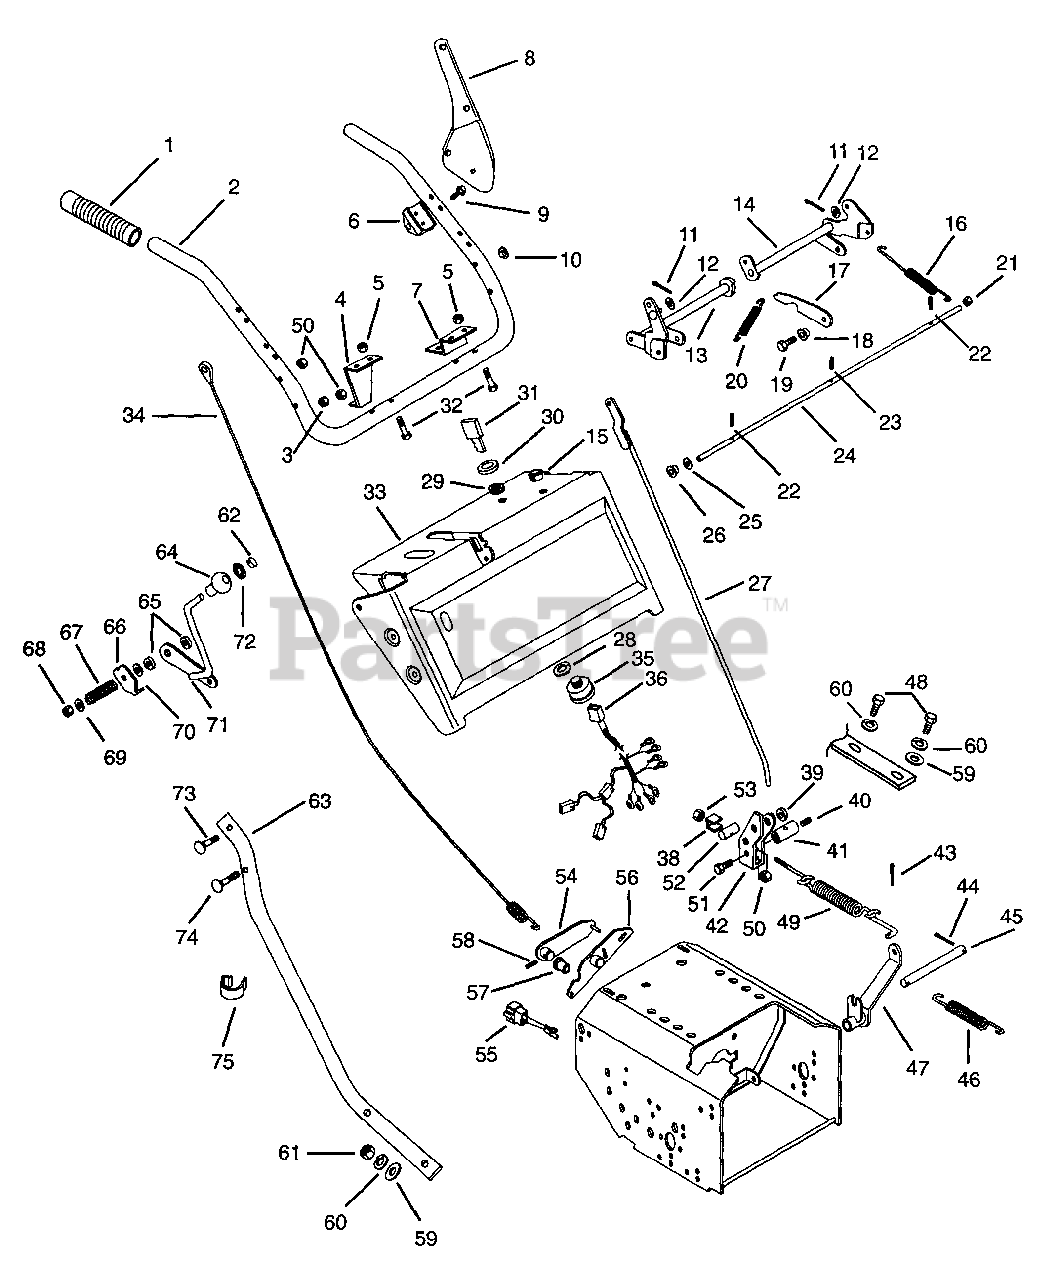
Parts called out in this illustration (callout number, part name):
1	HANDLE GRIP
2	UPPER HANDLEBAR
3	@NUT-SPNLK-FLG .312-18 YWZC
4	BRACKET, ROD
5	@NUT-LK-CTR .25-20 YWZC
6	HANDLE PIVOT
7	BRACKET, CHUTE CRANK
8	CLUTCH LEVER - COATED
8	LEVER, CLUTCH
9	SCR-TAP 12-24X1.50 CROVH YZ BT
11	@PIN-CTR .09X.50 EXTPRSQCT YWZ
12	@WSHR-FL-STL.281X.62X.065 YWZC
13	RH LEVER
14	LH LEVER
15	SNAP BUSHING
16	SG-TENS .051X.50X5.12 WLD 10.4
17	ARM, LATCH
18	BSHG-FLG .265X.437X.329X1.00
19	@BLT-HEX .25-20X.75 GR5 YWZC
20	SG-TENS .048X.44X1.75 WLD 9
21	NUT-CROWN .312-18 YWZC
22	PIN-ROLL .156X.75
23	PIN-ROLL .125X1.00
25	@WSHR-FL-STL.344X.688X.065YWZC
26	BSHG-FLG .325X.465X.333X.685
27	TRACTION CLUTCH ROD
28	WSHR-LK-INT .625X.045 YWZC
29	NUT-PANEL .625-32 GRECO
30	CAP - IGNITION SWITCH
31	KEY -W/CAP
32	@BLT-HEX .25-20X1.50 GR5 YWZC
33	PANEL W/DECAL
33	PANEL - W/DECAL
34	CABLE, BLOWER CLUTCH
35	SWITCH ASSEMBLY
36	ST 12V HARNESS
38	ADAPTER SPACER
39	SPACER 1.00 X .64 X .38
40	SCR-SET .32-18X.38 SKHCUPNL OH
41	ROD ADAPTER
42	CLUTCH ENGAGEMENT YOKE
43	@PIN-CTR .09X.50 EXTPRSQCT YWZ
44	@PIN-CTR .09X1.00 EXTPRSQCT YZ
45	ROD, FORK PIVOT
46	SG-TENS .080X.73X3.06 WLD 20
47	FORK, CLUTCH
48	@BLT-HEX .38-16X1.00 GR5 YWZC
49	SPRING ASSEMBLY
50	@NUT-LK-CTR .31-18 YWZC
51	@BLT-HEX .31-18X.75 GR5 YWZC
52	ADAPTER
53	@NUT-LK-NYL .312-18 YWZC
54	LEVER CLUTCH
55	JUMPER
57	BSHG-FLG.500X.625X.312X.750NY
58	PIN-ROLL .156X.88
59	@WSHR-FL-STL.438X1.00X.083 YWZ
60	WSHR-LK .375X.115 HVY YWZC
61	@NUT-HEX .38-16 YWZC
62	HOLE PLUG
63	HANDLEBAR, L.H. LOWER
63	HANDLEBAR, R.H. LOWER
64	KNOB
65	FRICTION WASHER
66	PRESSURE FLANGE
67	SG-COMP .187X.56X1.62
68	@NUT-LK-CTR .38-16 YWZC
69	@WSHR-FL-STL.406X.812X.065 YWZ
70	SPACER .406X.620X.125
71	LEVER-DEFLECTOR
72	RG-RTNG-EXT .375X.010
73	@BLT-RDHDSQNK .31-18X1.75 G5YZ
74	BLT-RDHDSQSHNK.31-18X2.75G2YWZ
